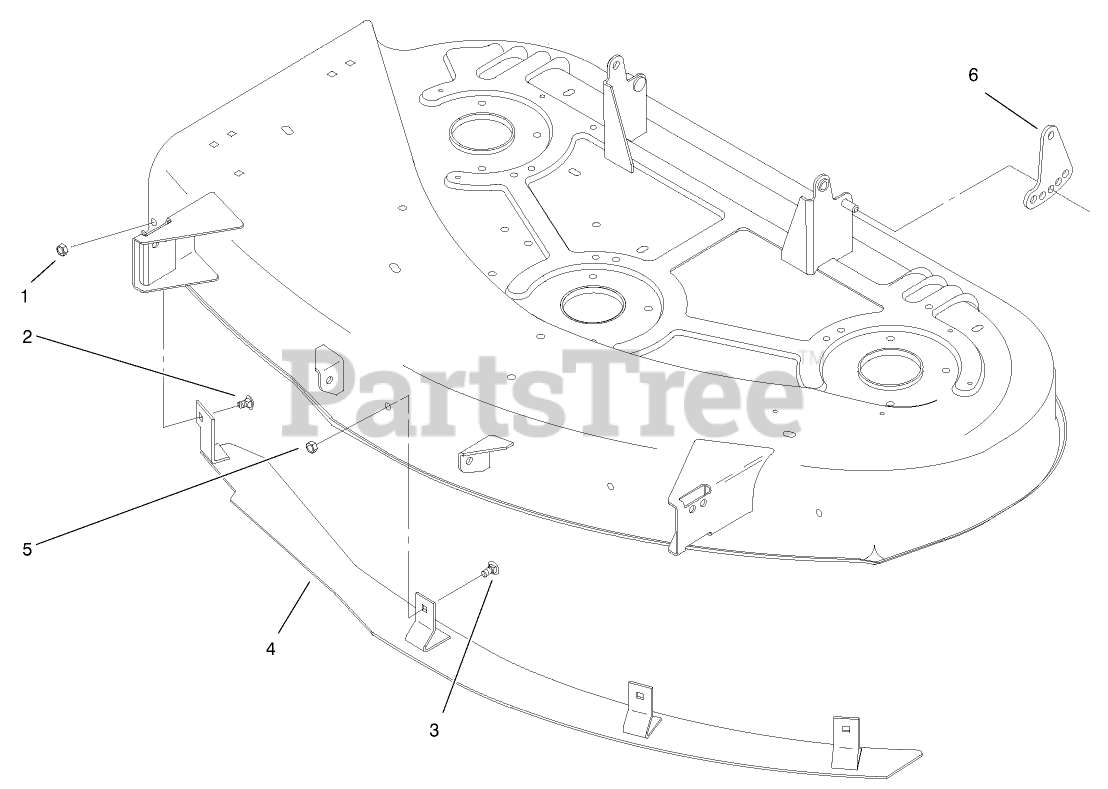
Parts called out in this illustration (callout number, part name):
1	NUT-LOCK, NI
2	BOLT-CARR
3	SCREW-CARR
5	NUT-LOCK, NI
6	LINK-ADJUSTING, HOC
